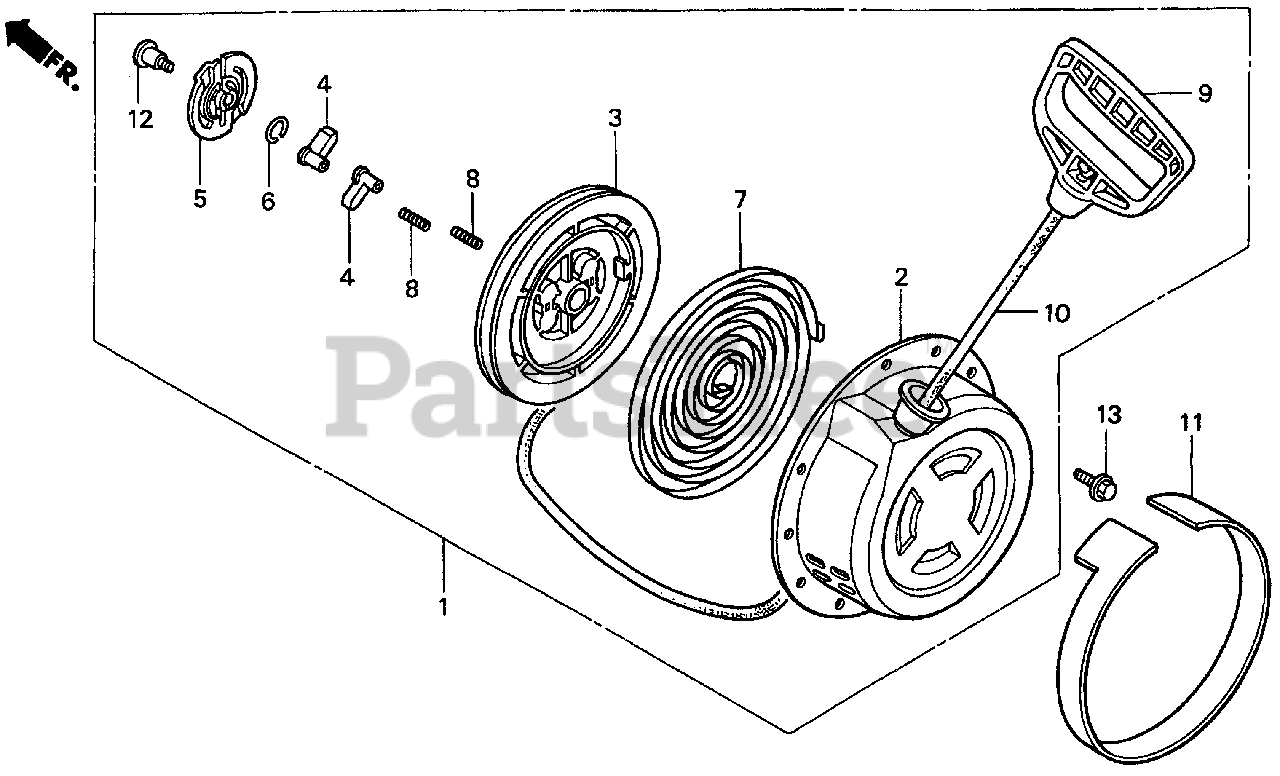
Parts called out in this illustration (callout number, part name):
1	STARTER ASSY., RECOIL *R8* (BRIGHT RED)
2	CASE, RECOIL STARTER
3	REEL, RECOIL STARTER
4	RATCHET, STARTER
5	GUIDE, RATCHET
6	SPRING, FRICTION
7	SPRING, RECOIL STARTER
8	SPRING, RETURN
9	GRIP, STARTER
10	ROPE, RECOIL STARTER (#5X55") (NA USE ALT:08550-ZG921-11)
11	PLATE, RECOIL STARTER
12	SCREW, SETTING
13	BOLT, FLANGE (6X10)
